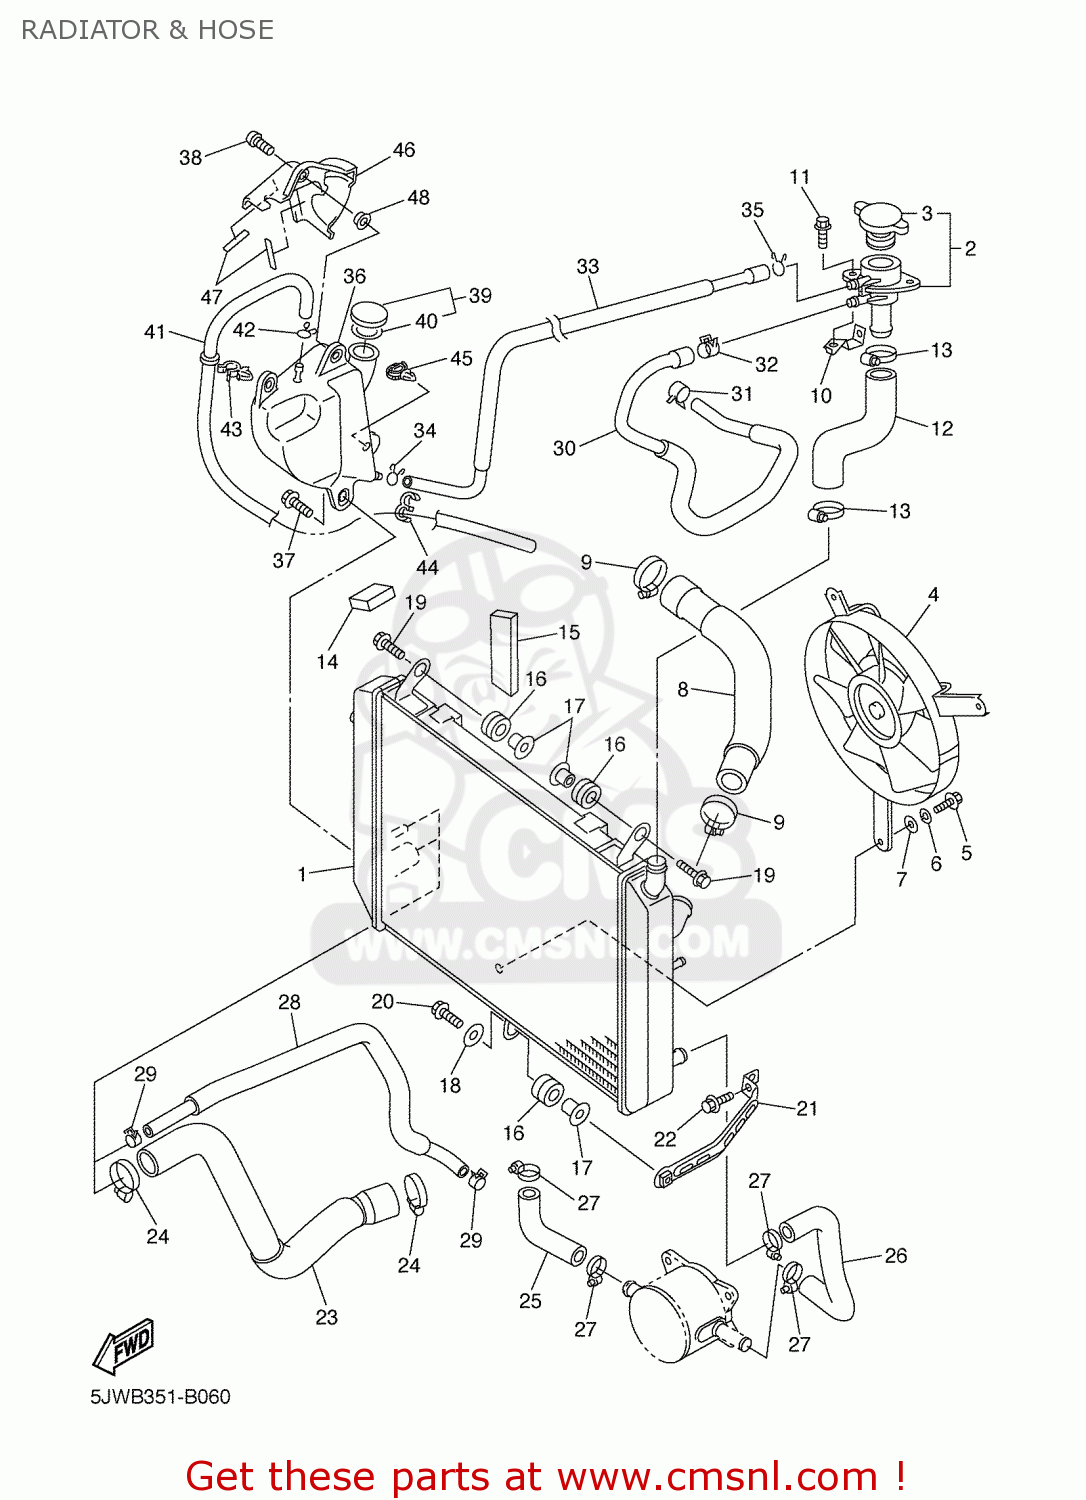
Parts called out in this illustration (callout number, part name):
01	RADIATOR ASSY
02	CONDUCTION ASSY
03	CAP, RADIATOR
04	BLOWER ASSY
05	BOLT
06	WASHER, SPRING
07	WASHER(6TA)
08	HOSE 5
09	HOSE CLAMP ASSY(3GM)
10	BRACKET 1
11	BOLT, FLANGE(4MY)
12	HOSE,3
13	HOSE CLAMP ASSY(1YL)
14	DAMPER, AIR SHROUD 2
15	DAMPER, AIR SHROUD 3
16	GROMMET (29L)
17	COLLAR
18	WASHER (802-77179-00)
19	BOLT, FLANGE(JN5)
20	BOLT, FLANGE(4MY)
21	STAY, RADIATOR
22	BOLT, FLANGE(8BA)
23	HOSE 6
24	HOSE CLAMP ASSY(3GM)
25	HOSE 7
26	HOSE 8
27	HOSE CLAMP ASSY(2LJ)
28	HOSE 1
29	CLIP (26H)
30	HOSE 2
31	CLIP (26H)
32	CLIP (29L)
33	HOSE, 4
34	CLIP (806-24356-00)
35	CLIP 1432435600
36	TANK, RECOVERY
37	BOLT, WITH WASHER(55K)
38	BOLT, WITH WASHER (30X)
39	CAP
40	GASKET (NAS)
41	HOSE (L840)
42	CLIP (806-24356-00)
43	CLAMP(3LD)
44	CLAMP(56R)
45	CLAMP
46	BRACKET, RECOVERY TANK
47	DAMPER
48	COLLAR (26H)
